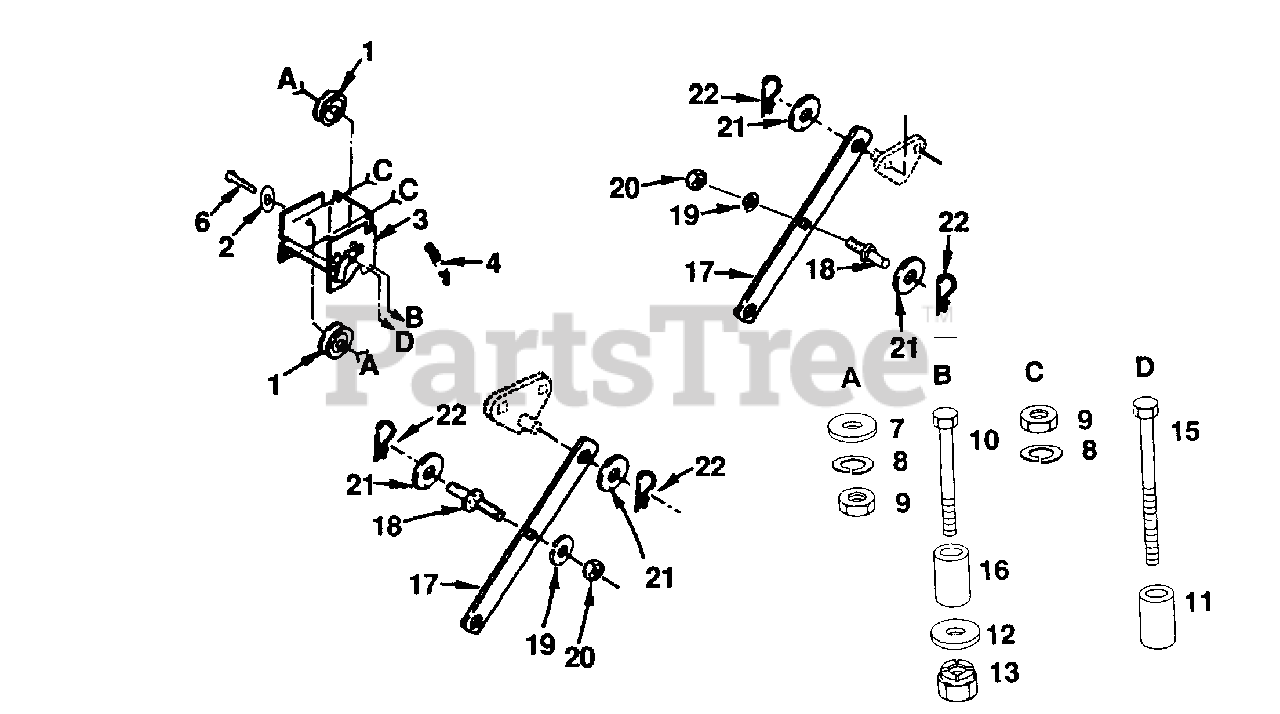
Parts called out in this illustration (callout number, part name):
1	Pulley, Idler (AYP part number)
2	Washer 13/32 x 2-3/8 x 8 Gauge (AYP part number)
3	Bracket, Idler (AYP part number)
4	Spring (AYP part number)
6	Bolt, Hex 3/8-16 x 2 (AYP part number)
7	Washer 13/32 x 7/8 x 13 Gauge (AYP part number)
8	Washer, Lock 3/8 (AYP part number)
9	Nut, Hex 3/8-16 (AYP part number)
10	Bolt, Hex 5/16-18 x 1 (AYP part number)
11	Bushing, Handle, Clutch (AYP part number)
12	Washer 11/32 x 7/8 x 16 Gauge (AYP part number)
13	Nut, Crownlock 5/16-18
15	Bolt, Hex 3/8-16 x 2-1/4 (AYP part number)
16	Spacer (AYP part number)
17	Arm, Suspension (AYP part number)
18	Stud, Pivot Center (AYP part number)
19	Washer, Lock 1/2 (AYP part number)
20	Nut, Hex 1/2-13 (AYP part number)
21	Washer 17/32 x 1-1/6 x 13 Gauge (AYP part number)
22	Retainer Spring (AYP part number)
